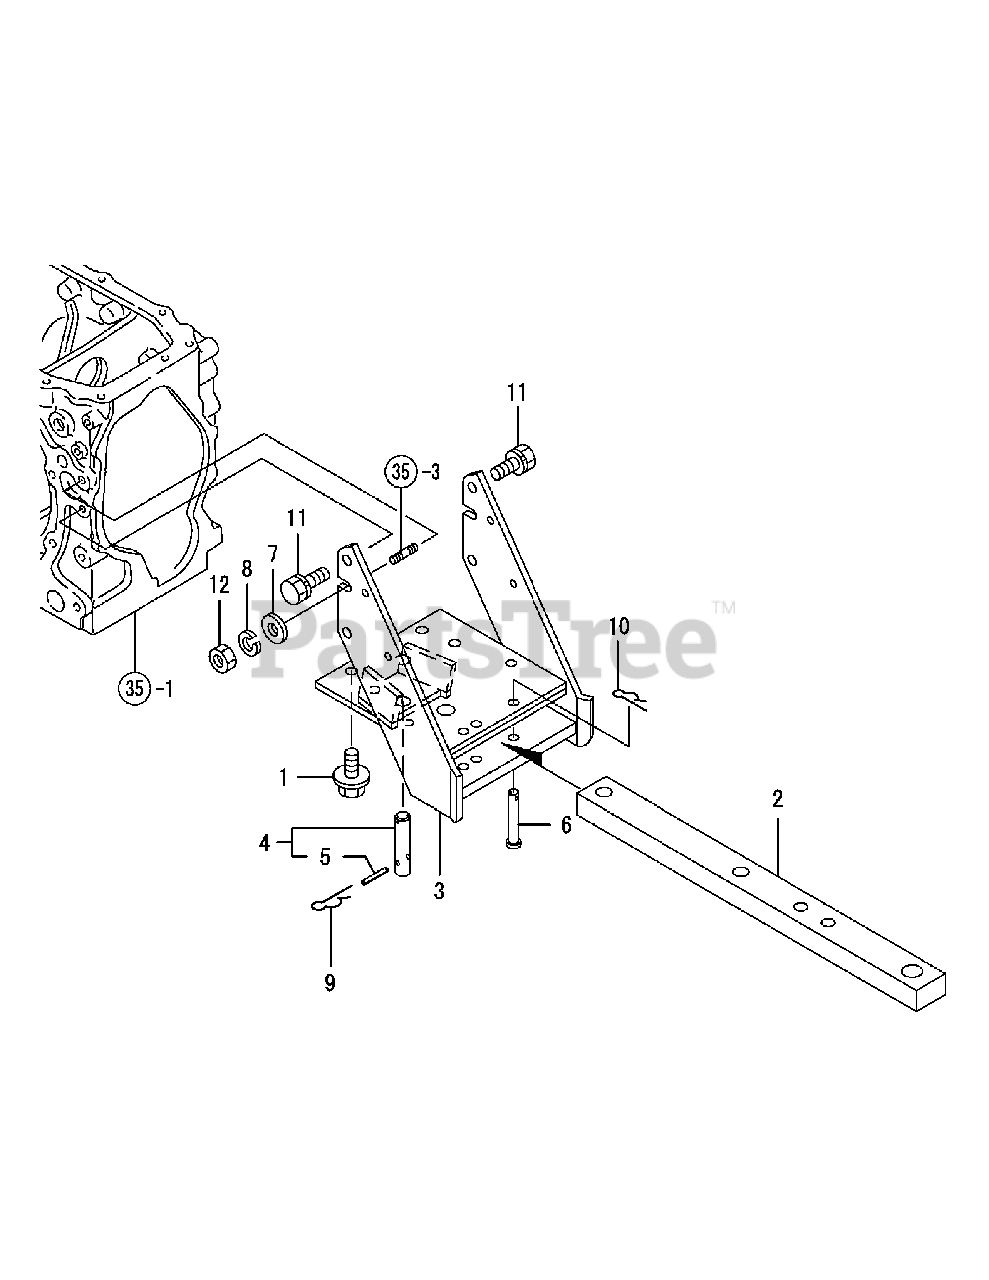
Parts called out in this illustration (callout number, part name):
2	HITCH, DRAWBAR
3	BRACKET, DRAWBAR
5	SPRING PIN 6X40
7	WASHER 12,POLISHED
8	SPRING WASHER 12
11	BOLT W/WASHER M12X30
